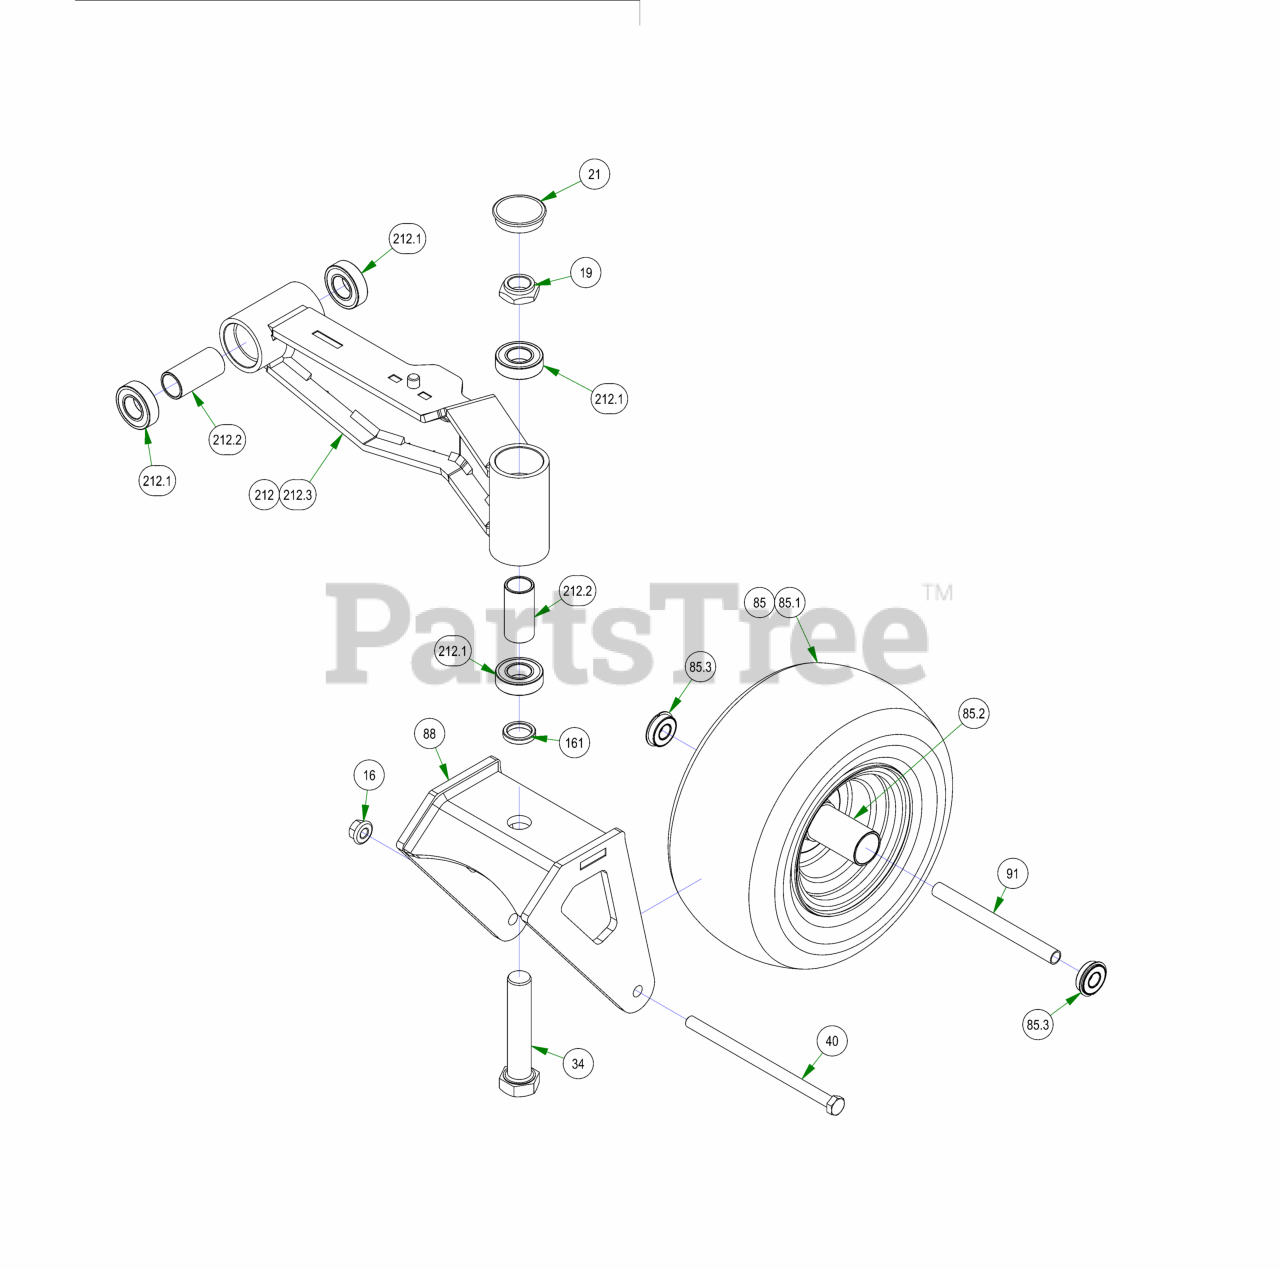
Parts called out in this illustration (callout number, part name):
16	1/2-13 NYLON INSERT FLANGE LOCKNUT ZINC
19	1"-14 NYLON INSERT JAM LOCKNUT ZINC
21	2017 Bearing Cover
34	1"-14 X 5 HEX CAP SCREW (GR.8) ZINC YELLOW
40	1/2-13 X 8-1/2 HEX CAP SCREW (GR.5) ZINC
85	13x6.5-6 Black Tire and Wheel Assembly
85.1	13 x 6.50 - 6 Tire
85.2	Front Tire Rim
85.3	Ball Bearing w/Retainer, 99502H-NR, .625 Bore x 1.375 OD x .4375 Width
88	2019 Stand-on Front Fork Weldment
91	Front Wheel Spanner
161	Spacer, 1x1.375x.25
212	2021 Maverick LH Front Suspension Arm Assy (48", 54" & 60")
212.1	1641 BEARING W/2 CONTACT RUBBER SEALS
212.2	2016 Front Bearing Spacer
212.3	2021 Maverick I-Beam Front Arm LH Weldment - Painted
